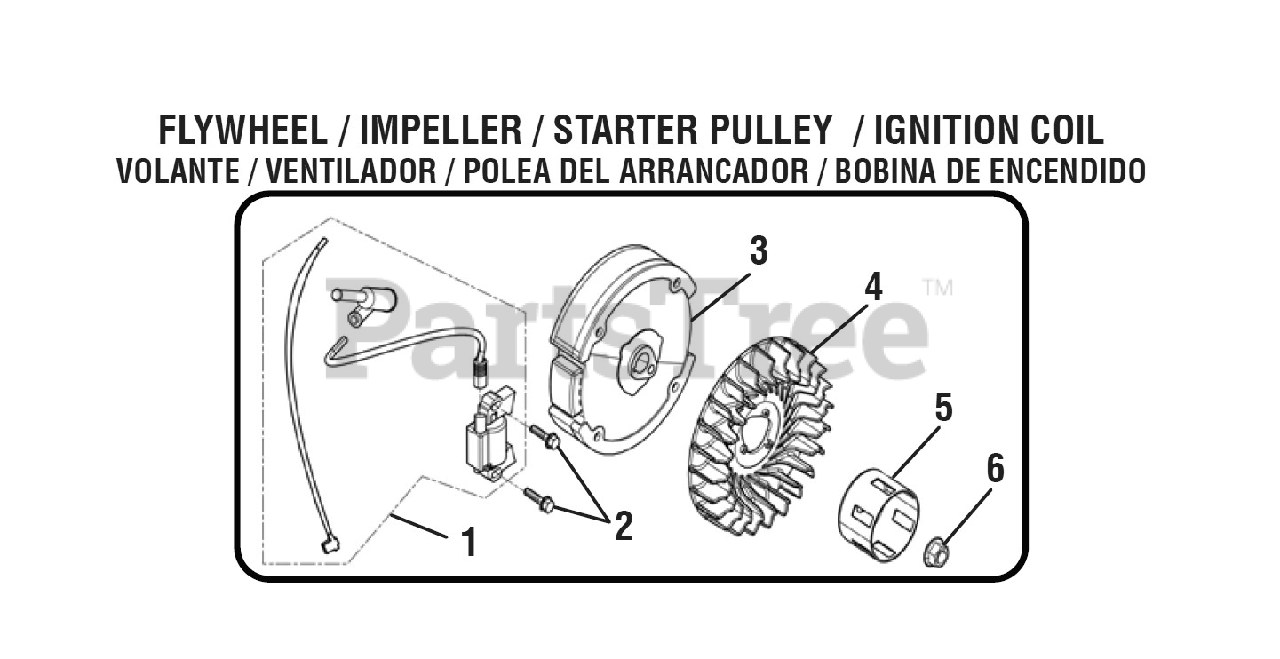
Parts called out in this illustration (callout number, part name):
1	Ignition Coil
3	Flywheel Assembly
4	Impeller
5	Starter Pulley
6	Flywheel Nut
